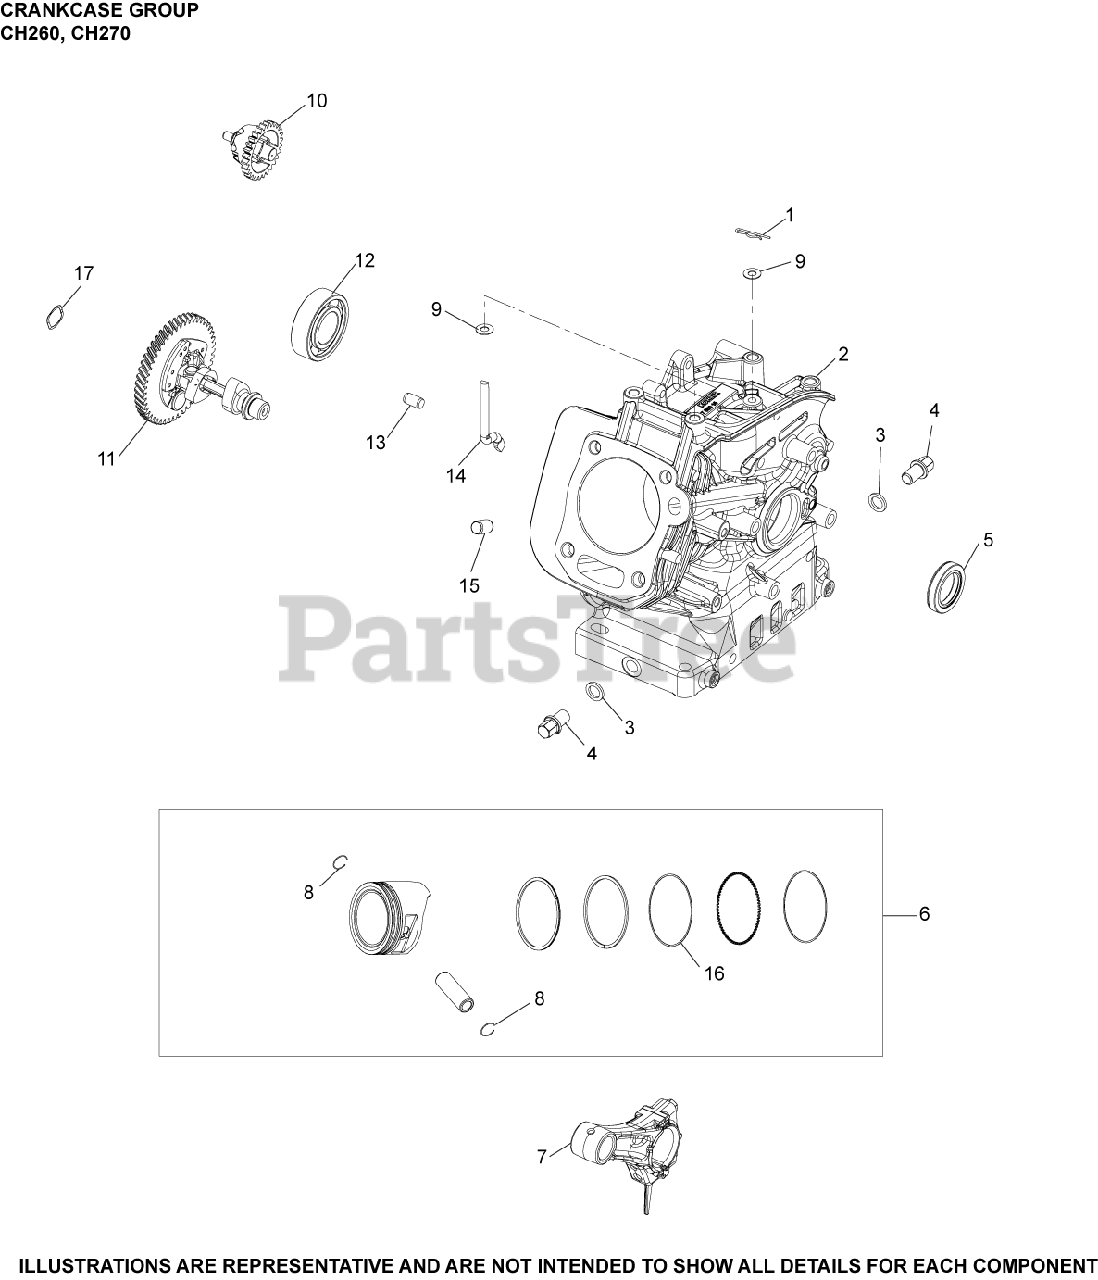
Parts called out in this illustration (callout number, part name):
1	CLIP, GOVERNOR SHAFT
2	CRANKCASE ASSEMBLY
3	WASHER, DRAIN PLUG - (#1846801S)
4	KIT, DRAIN PLUG
6	KIT, PISTON
7	ROD, CONNECTING ASSEMBLY
8	RETAINER, PISTON PIN
9	WASHER, FLAT (13MM OD)
10	GOVERNOR ASSEMBLY
11	CAMSHAFT ASSEMBLY
13	PIN, DOWEL
14	SHAFT, GOVERNOR CROSS
15	DOWEL, CYLINDER HEAD-(#1438013S)
19	PIN, PISTON
